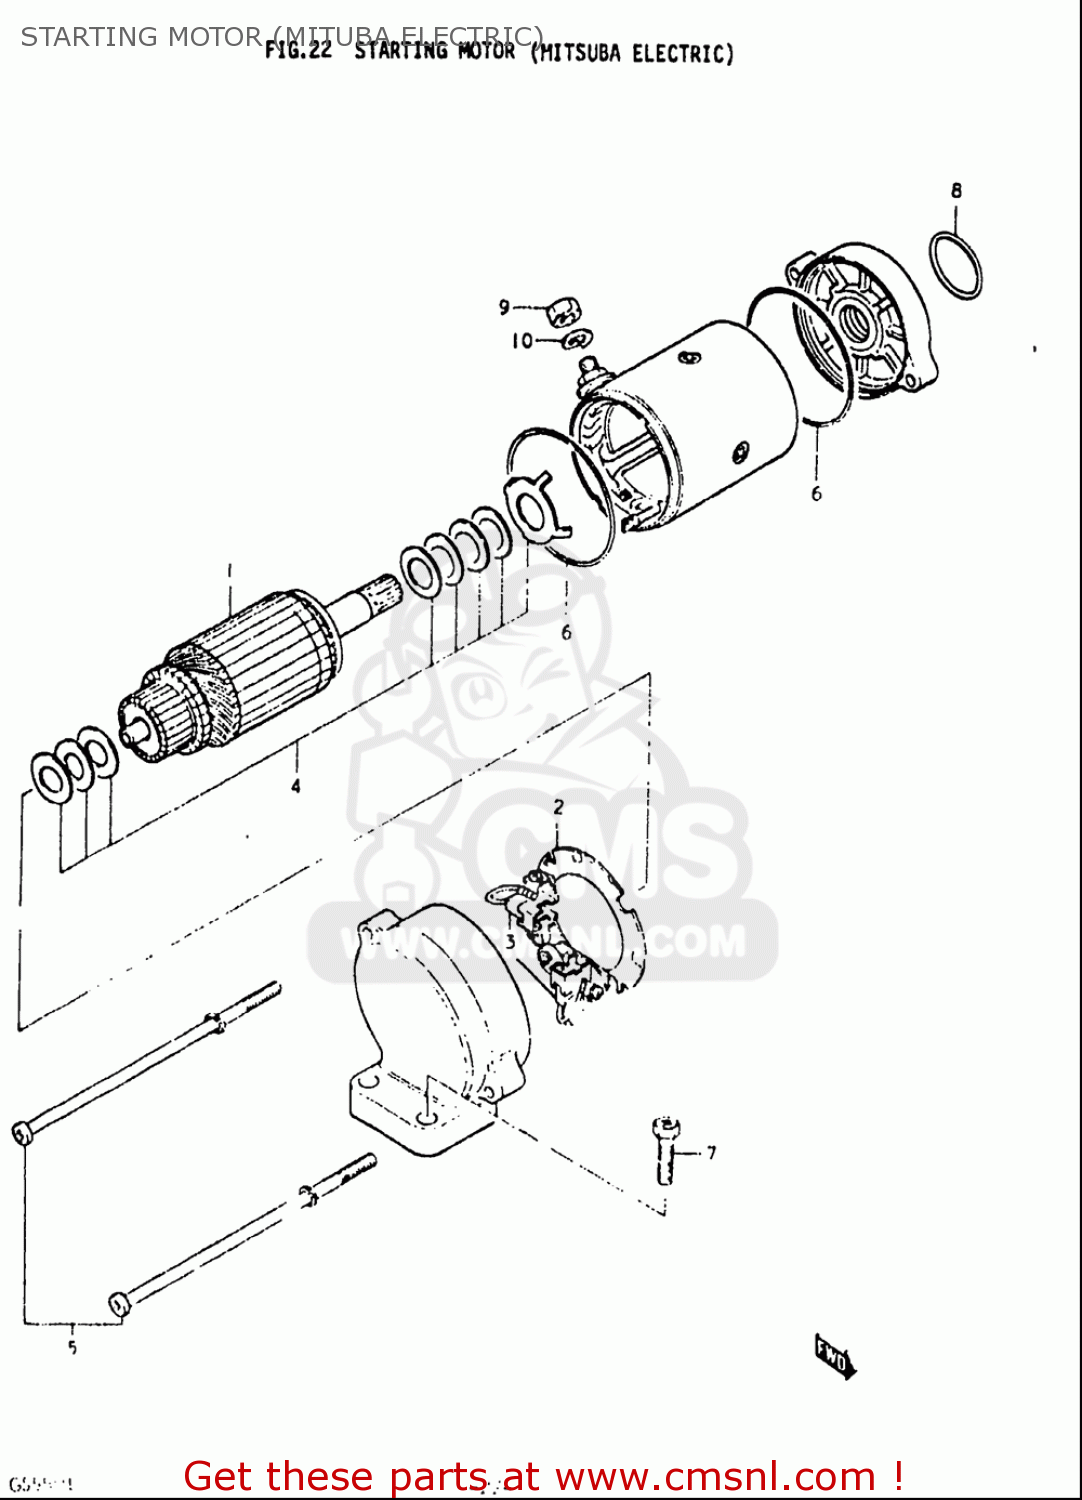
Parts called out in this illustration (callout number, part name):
2	HOLDER ASSY
3	BRUSH SET
5	BOLT
6	O RING
7	SCREW (6X25)
8	O RING(D:2,ID:24.5)
9	NUT
10	WASHER,LOCK
